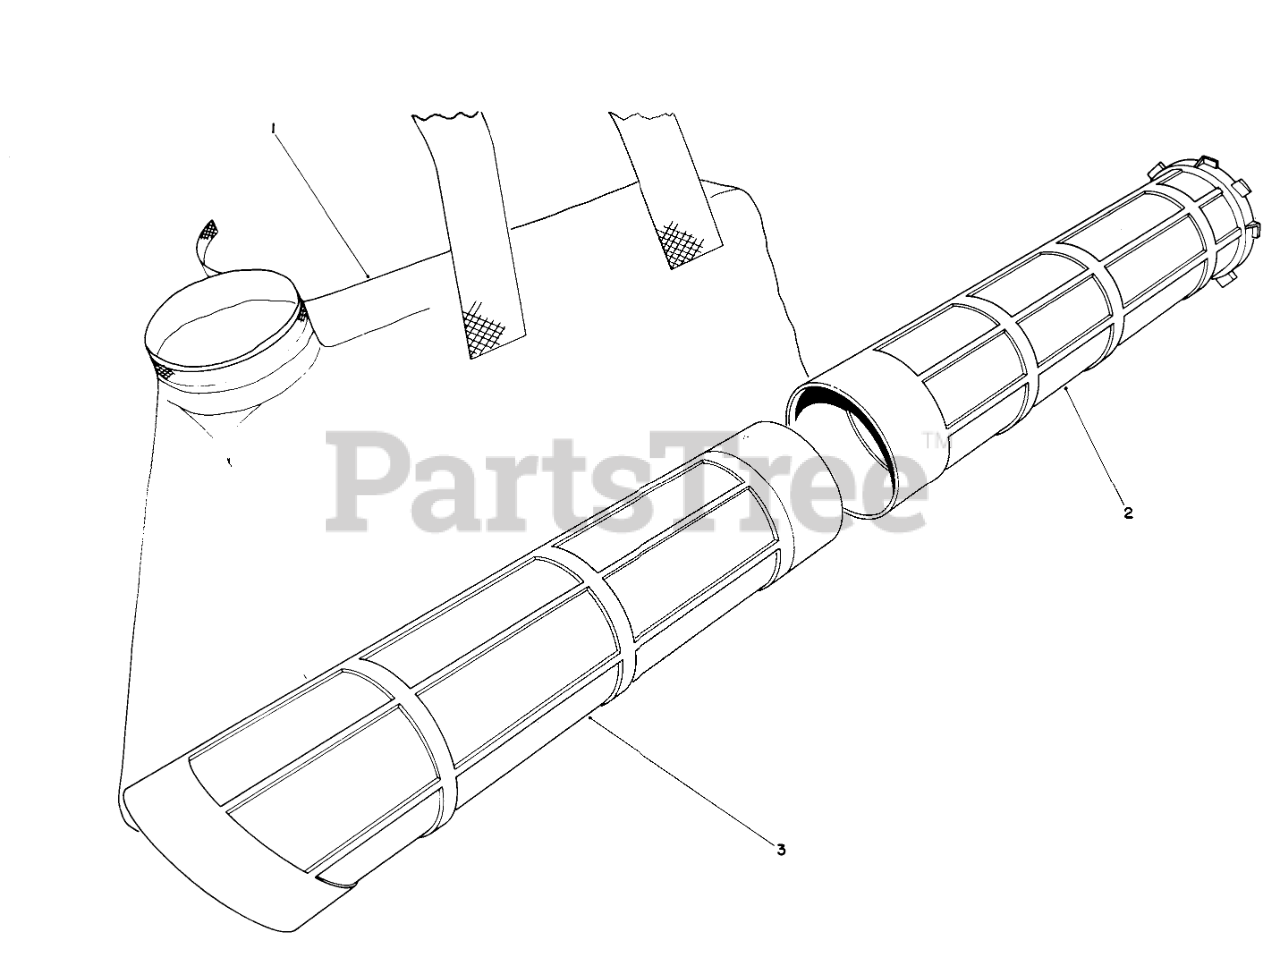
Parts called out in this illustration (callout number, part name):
1	Bag-Vacuum
2	Tube-Upper Vacuum
3	Tube-Lower Vacuum
